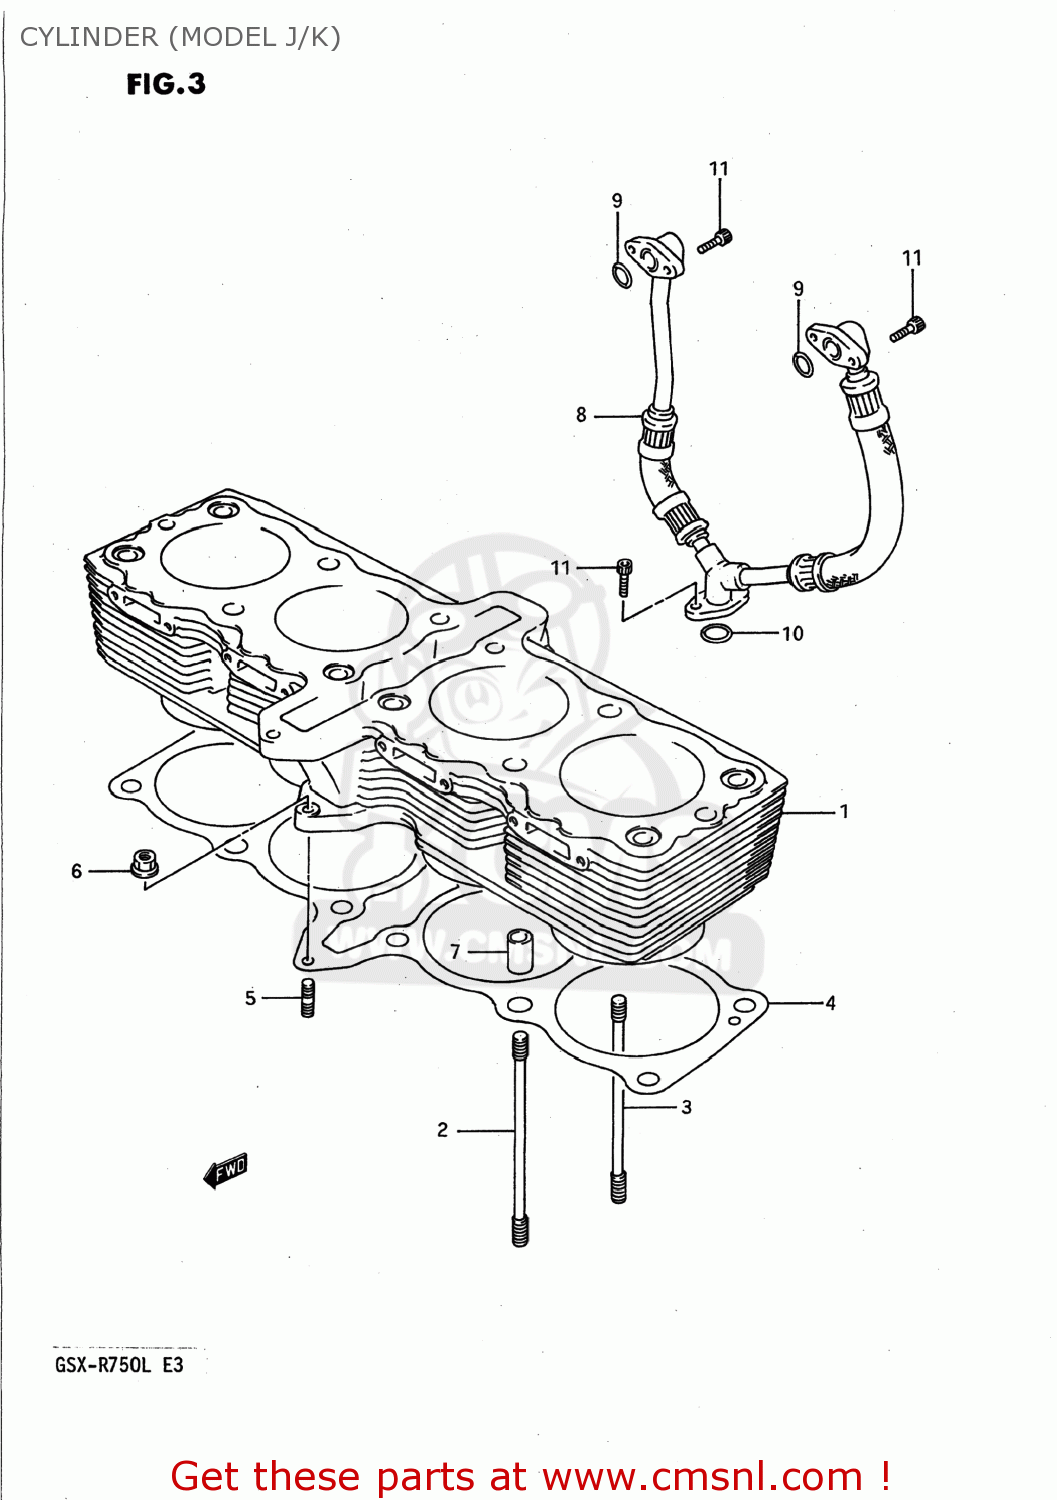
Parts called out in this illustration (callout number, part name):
1	CYLINDER
2	BOLT,STUD
3	BOLT,STUD
4	GASKET,CYLINDER (NAS)
5	STUD BOLT L:20
6	NUT 6MM
7	PIN
8	HOSE
9	O RING(D:2.5,ID:13.8)
10	O RING(D:2.4,ID:15.8)
11	BOLT
